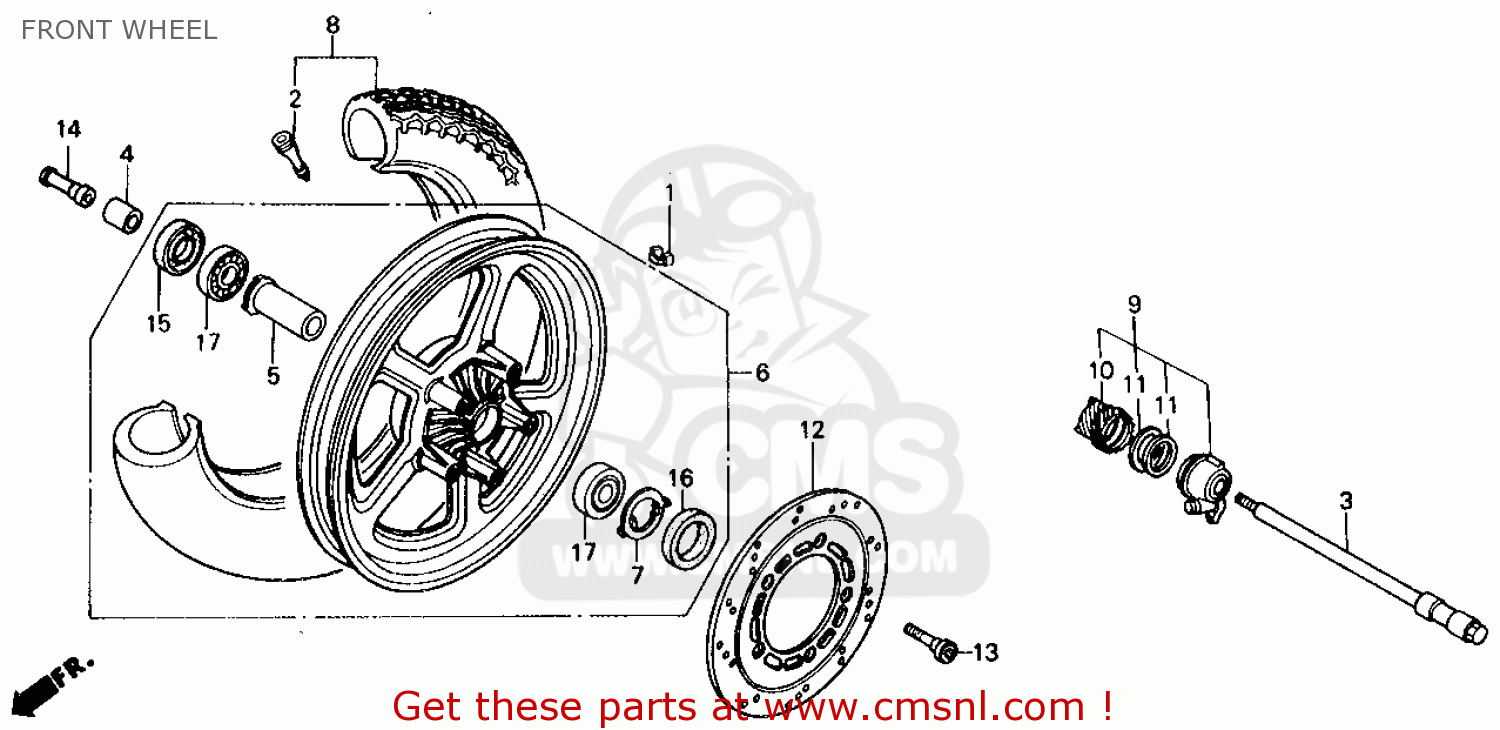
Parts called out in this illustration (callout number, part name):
1	WEIGHT,BAL.20G
2	VALVE,RIM(BS)
3	AXLE,FR.WHEEL
4	COLLAR,FR.WHEEL
5	COLLAR.FR,DISTANC
6	WHEEL SET,FR
7	RETAINER,GEAR BOX
8	TIRE (100/90-19)
9	GEAR BOX SPDMT
10	GEAR,SPEEDOMETER
11	WASHER,SPDMT.GEAR
12	DISK,FR BRAKE
13	BOLT,FR.DISK 8X24
14	NUT,AXLE,14MM
15	DUST SEAL,22X42X7
16	DUST SEAL,40X50X5
17	B/BRG RAD N/COM
